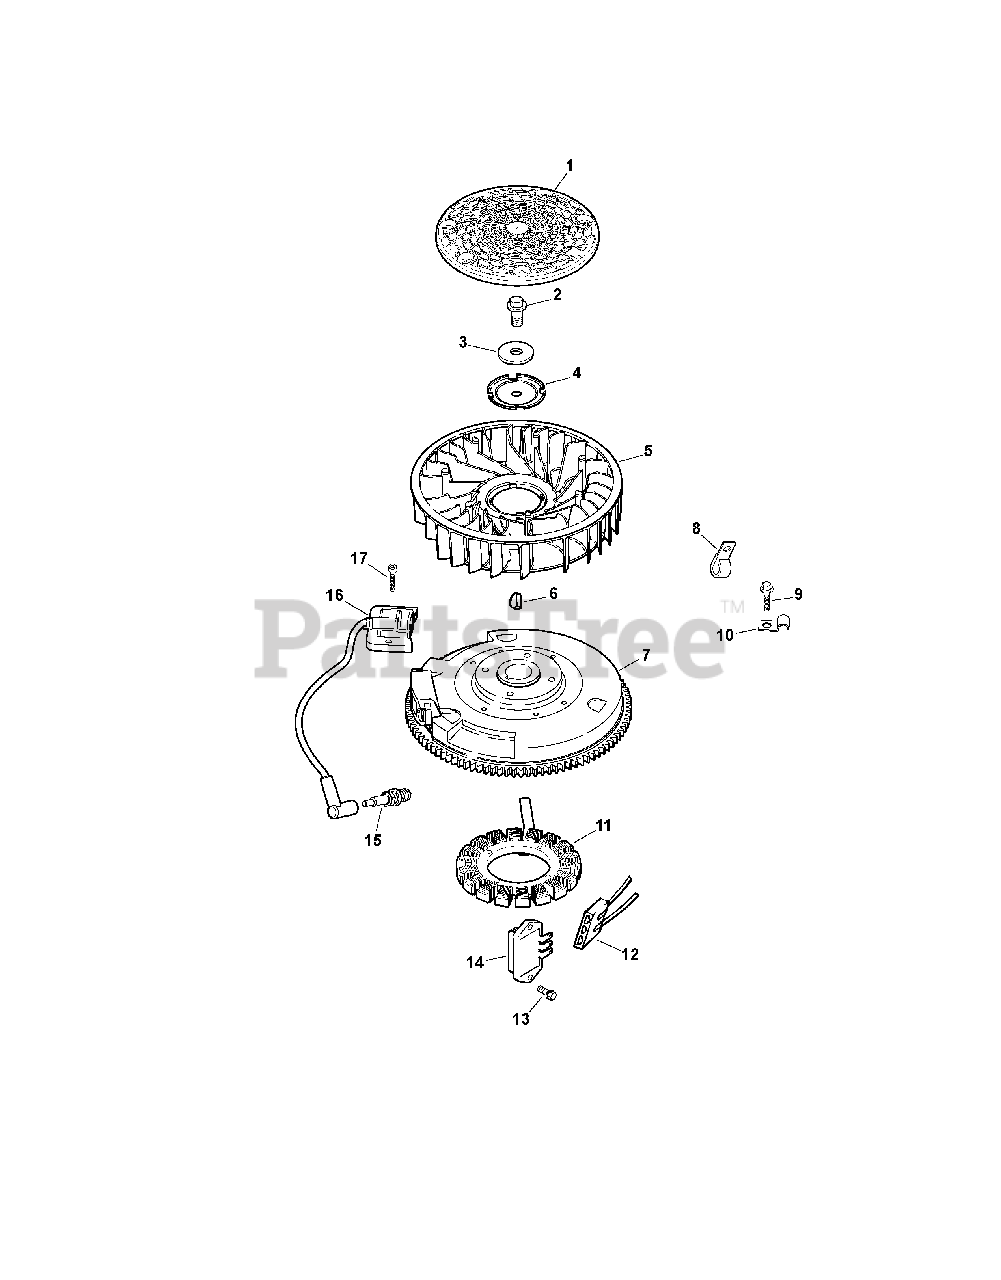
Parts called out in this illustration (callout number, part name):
2	Hex Flange Screw (M10 x 1.5 x 46)
3	Spring Washer
4	Fan Mounting Plate
6	Woodruff Key
7	Flywheel
11	Stator Assembly
12	Connector (3 Contact)
13	Hex Flange Screw (M5 x .8 x 20)
14	Regulator Rectifier
15	Spark Plug
16	Ignition Module
17	Hex Flange Screw (M5 x .8 x 25)
